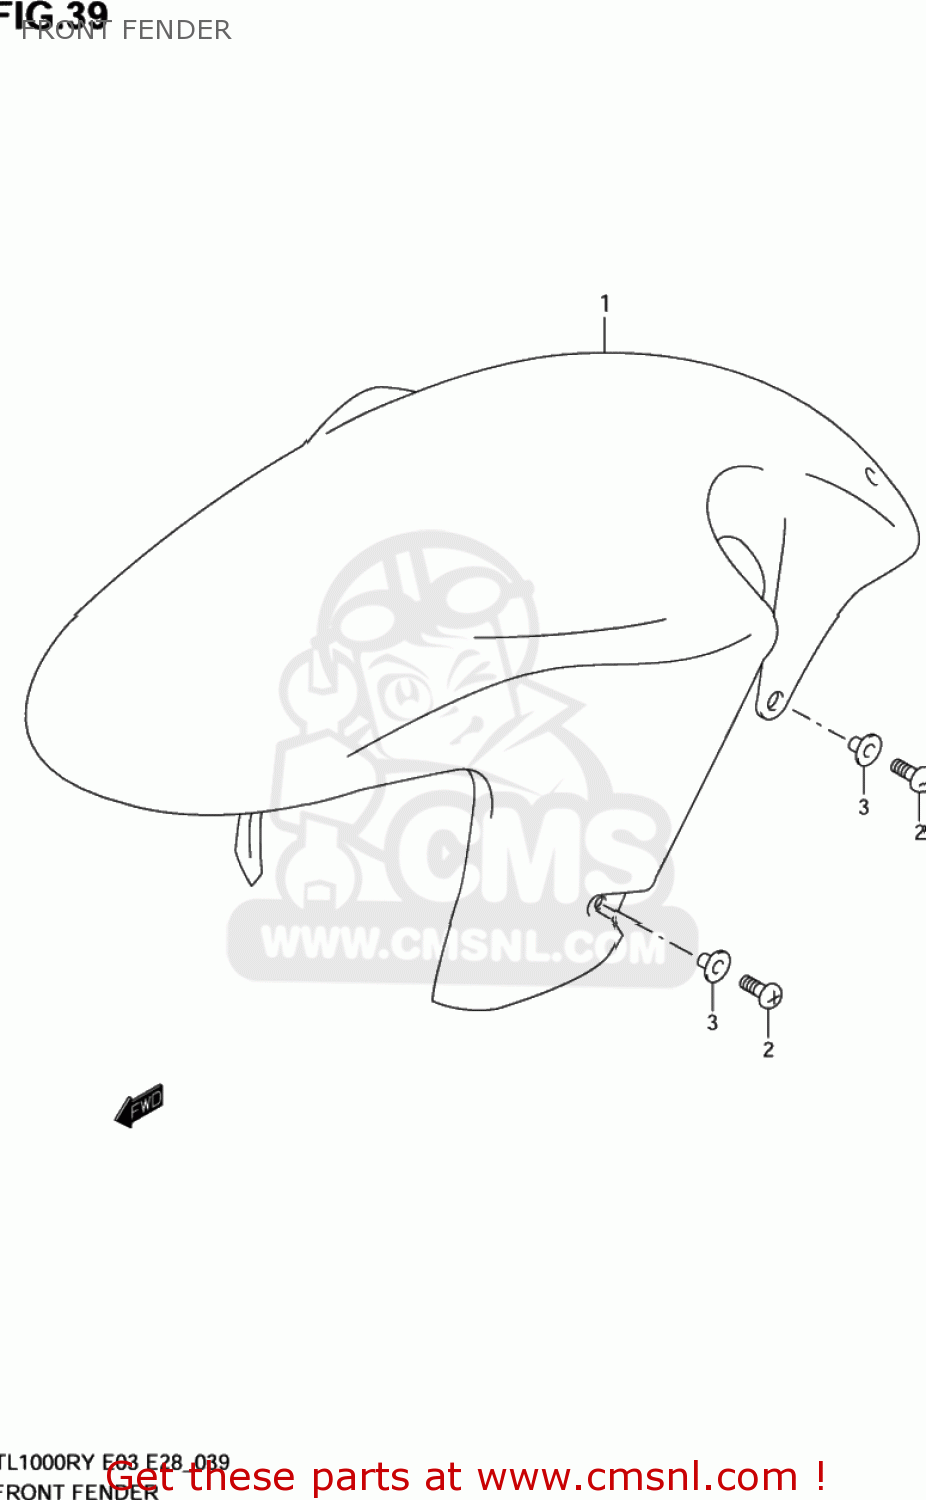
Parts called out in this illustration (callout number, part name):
1	FENDER COMP,FRONT
2	SCREW(6X16)
3	WASHER(6.3X16X1.5)
